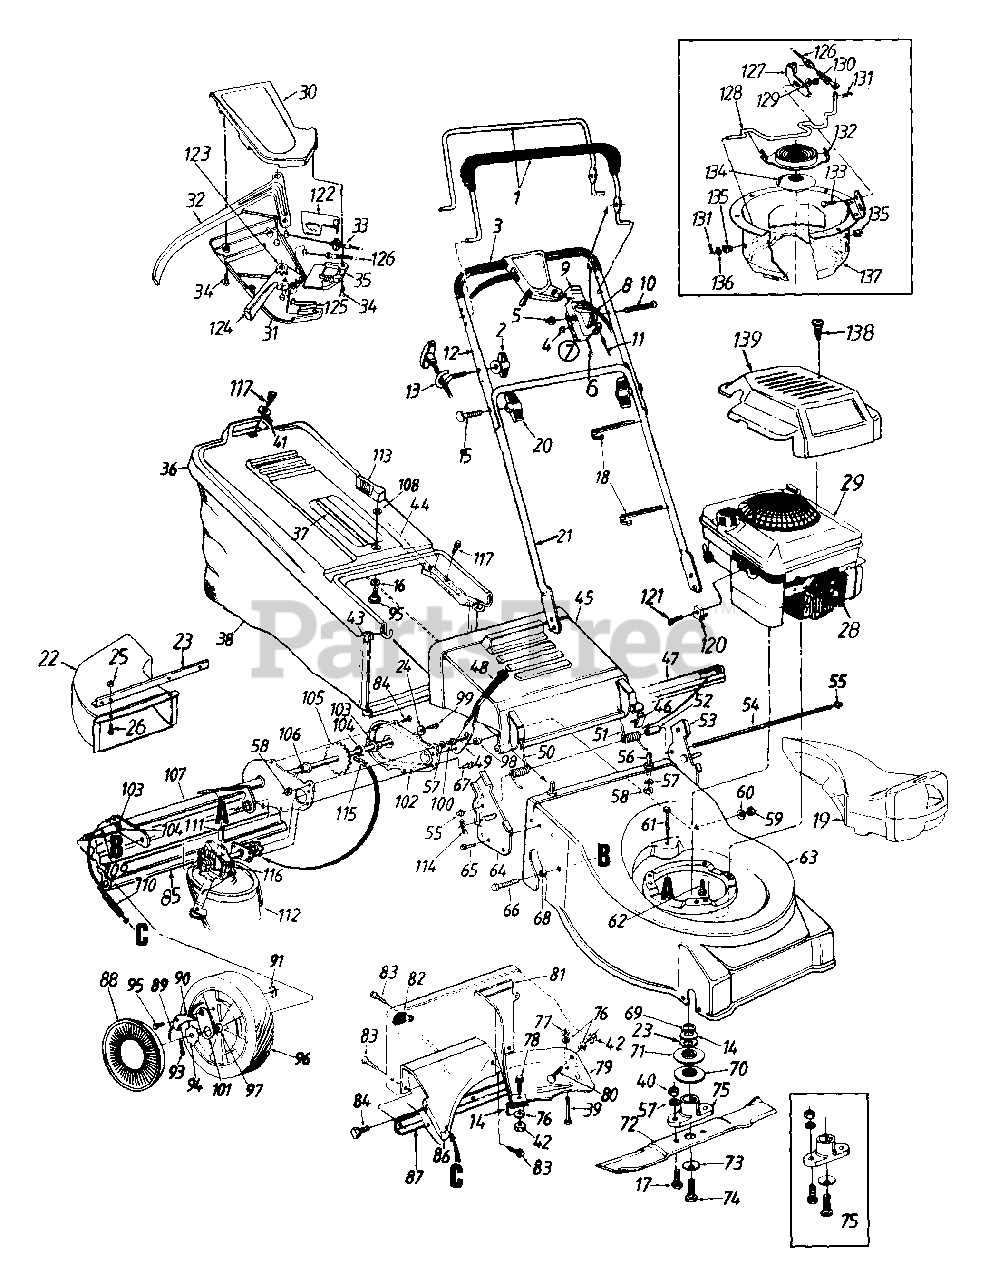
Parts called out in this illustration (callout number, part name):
1	Std. Control Handle
1	Deluxe Control Handle
2	Handle Knob 1/4-20 Thd.
3	Foam Grip
4	Spr. Wash..66" I.D.
5	Hex L-Nut 1/4-20 Thd.
6	Throttle Cable - 55"
7	Throttle Box Comp.
8	Throttle Lever
9	Throttle Body
10	Oval C-Sunk Scr.
11	Control Cable - 40.5"
12	Upper Handle
13	Rope Guide
14	Stop Bracket
15	Curved Hd. Bolt 5/16-18 x 2"
16	Bowed Washer
17	Hex Bolt 3/8-24 x 1" Lg.
18	Cable Tie
19	Mulching Plug
20	Hand Knob
22	Chute Deflector
23	Chute Mounting Brkt.
24	Bell-Wash. .265" I.D. x .75"
25	Hex L-Nut 1/4-20 Thd.
26	Mach. Scr. 1/4-20 x .5" Lg.
28	Spark Plug Boot
29	Engine
30	Control Cover Half - Upper
31	Control Cover Half - Lower
32	Control Lever
33	Drive Cable - 51" Lg.
34	Flat C-Sunk Hd. Tap Scr. #10 x .75" Lg.
35	S.P. Control Cover
36	Hardtop Bag Cover
37	Hardtop Handle
38	Grass Bag
39	Truss Mach. Scr. 1/4-20 x 1.0" Lg.
40	Hex Nut 3/8-24 Thd.
41	Fl-Wash..281" I.D. x .62"
42	Hex Nut 1/4-20 Thd.
43	Front Catcher Frame
44	Rear Catcher Frame
45	Chute Deflector
46	Deflector Plug
47	Seal - Extrusion
49	Spring Lever
50	Torsion Spring - R.H.
51	Torsion Spring - L.H.
52	Spacer .255" I.D.
53	Handle Brkt. Ass'y. - L.H.
54	Hinge Pin 17.75" Lg.
55	Cap Speed Nut
56	Shld. Pin 3/8-24 x 1.43" Lg.
57	L-Wash. 3/8" I.D.
58	Hex Jam Nut 3/8-24 Thd.
59	Hex L-Nut 3/8-24 Thd.
60	Belt-Wash..38" I.D. x .88"
61	Hex Wash. Hd. Tap Scr. 1/4-20 x 1.5" Lg.
62	Hex L-Wash. Hd. Scr. 3/8-16 x 1" Lg.
63	21" Deck Ass'y.
64	Handle Brkt. Ass'y. - R.H.
65	Hex L-Wash. Hd. AB-Tap Scr. 1/4 x .62" Lg.
66	Hex Wash. Hd. Tap Scr. 3/8-16 x .75" Lg.
67	Hex Wash. Hd. Tap Scr. 1/4-20 x .5" Lg.
68	Spacer .383" I.D.
72	21" Blade
72	21" Mulching Blade
73	Bell-Wash. .46" I.D.
74	Hex Bolt 7/16-20 x 1.5" Lg.
75	Blade Adapter Kit
76	L-Wash. 1/4" I.D.
77	Hex Jam Nut 1/4-20 Thd.
78	Hex Bolt 1/4-20 x .85" Lg.
83	Torx Mach. AB-Tap Scr. 1/4 x .62" Lg.
84	Hex B-Tap Scr. 1/4 x .38" Lg.
85	Rear Flap
86	Rear Chute Baffle
87	Retaining Strip
88	Hub Cap
89	Plastic Spring
90	Pawl .345" I.D.
91	Weld Top L-Nut 1/4-20 Thd.
93	Cotter Pin 1/8" Dia.
94	Ratchet Wheel 1.62" O.D.
95	Shld. Bolt .342" Dia. x .268"
96	Wheel Ass'y. Comp. - Rear
97	Bearing 1/2" I.D.
98	Shld. Spacer .50" Dia.
99	Hex Bolt 1/4-20 x .62" Lg. (Gr. 5)
100	Shld. Pin 3/8-24 x 1.43" Lg.
101	Pawl Plate
104	Fl-Wash. .531" I.D. x .93"
105	Rear Axle Ass'y.
106	Hex Flange Bearing
110	Extension Spring 3.8" Lg.
111	Spacer .325" I.D.
112	V-Belt
113	Grass Catcher Locking Knob
114	Internal Cotter Pin 5/16" Dia.
115	#48 Chain .50" Pitch x 30 Links
116	Transmission Comp.
117	Hex L-Wash. Hd. AB-Tap Scr. 1/4 x .62" Lg.
120	Cable Clamp
121	Hex Self-Tap Scr. #10-32 x .62" Lg.
122	6-Speed Rack Cable Brkt.
123	3 Tooth Rack Gear Insert
124	6-Speed Shift Lever
125	Shift Lever Spring
126	Spd. Control Cable
127	Adjustable Cable Brkt.
128	Shift Rod
129	Bell-Wash. .265" I.D. x .75"
130	Hex Cent. L-Nut 1/4-20 Thd.
131	Cot-Pin 3/32" Dia. x .75" Lg.
132	Movable Pulley Half Ass'y.
133	Carr. Bolt 1/4-20 x .5" Lg.
134	Splined Pulley Half
135	Flanged Bushing
136	Fl-Wash. .328" I.D. x .68" O.D.
137	Housing Ass'y.
138	Hi-Lo Scr. #10 x 1.25" Lg.
139	XTE Engine Shroud
